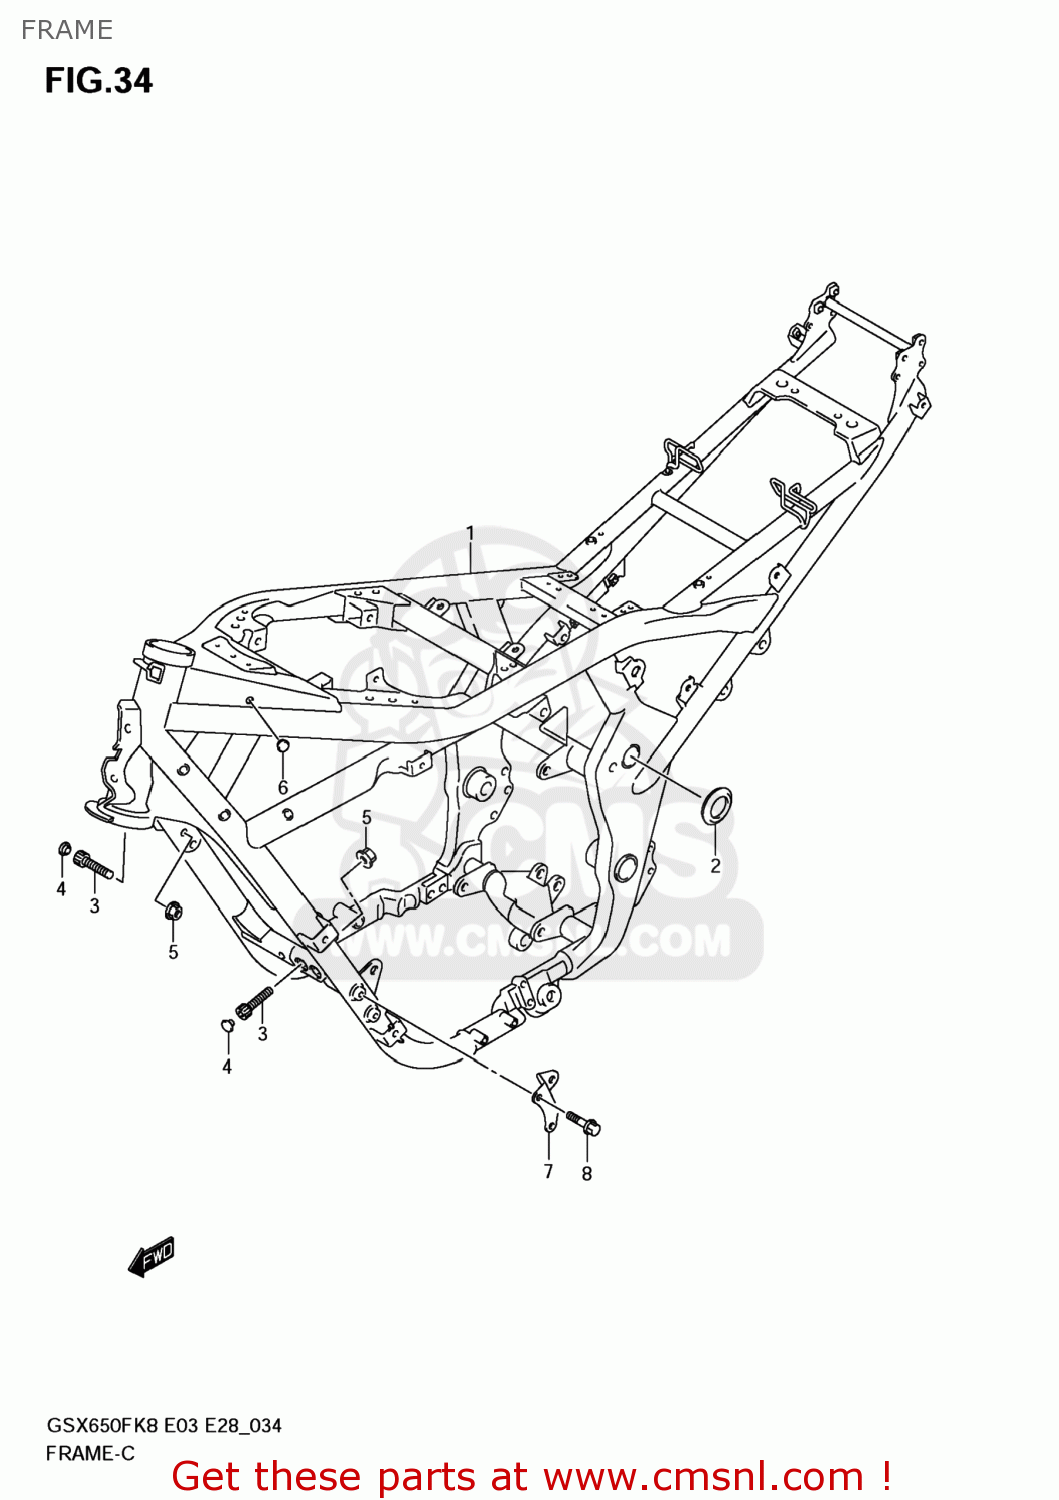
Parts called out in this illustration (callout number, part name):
1	FRAME(BLACK)
2	CAP,FRAME PIVO
3	BOLT(10X37)
4	CAP(OD:12)
5	NUT
6	PLUG(OD:17)
7	BRACKET,ENGINE MOUNTING FR
8	BOLT
